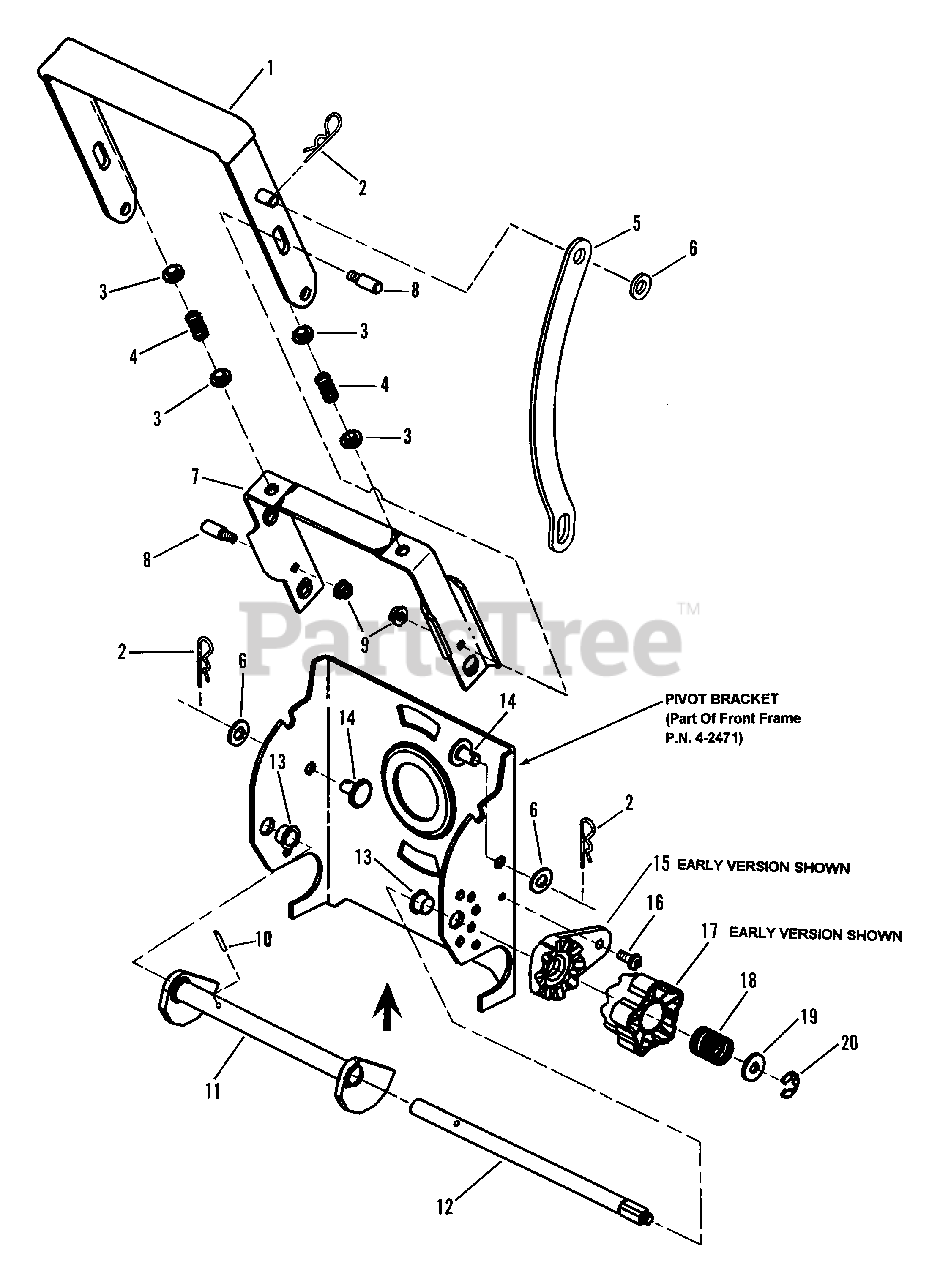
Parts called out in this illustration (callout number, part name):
1	HANDLE, Deck Lift
2	HAIRPIN, 3/32 x 1-1/2"
3	PLUG, Spring Retainer
4	SPRING
5	BAR, Deck Lift
6	WASHER, 3/8" Flat
7	LEVER, Deck Lift Handle Release
8	PIN, Deck Lift Handle
9	NUT, 1/4-20 Hex Flange Lock, Grade 5
10	PIN, 1/8" x 1" Roll
11	CAM, Deck Lift
12	SHAFT, Deck Height Cam
13	BEARING, Nylon
14	PIN, 3/8 x 1/2" Large Head Clevis
15	DETENT, Height Cam
16	SCREW, 1/4-20 x 5/8" Pan Head, Self-Tapping
17	KNOB, Height Cam Detent
18	SPRING, Deck Height Handle
19	WASHER, 5/16" Flat
20	RING, .2 98 Retaining
